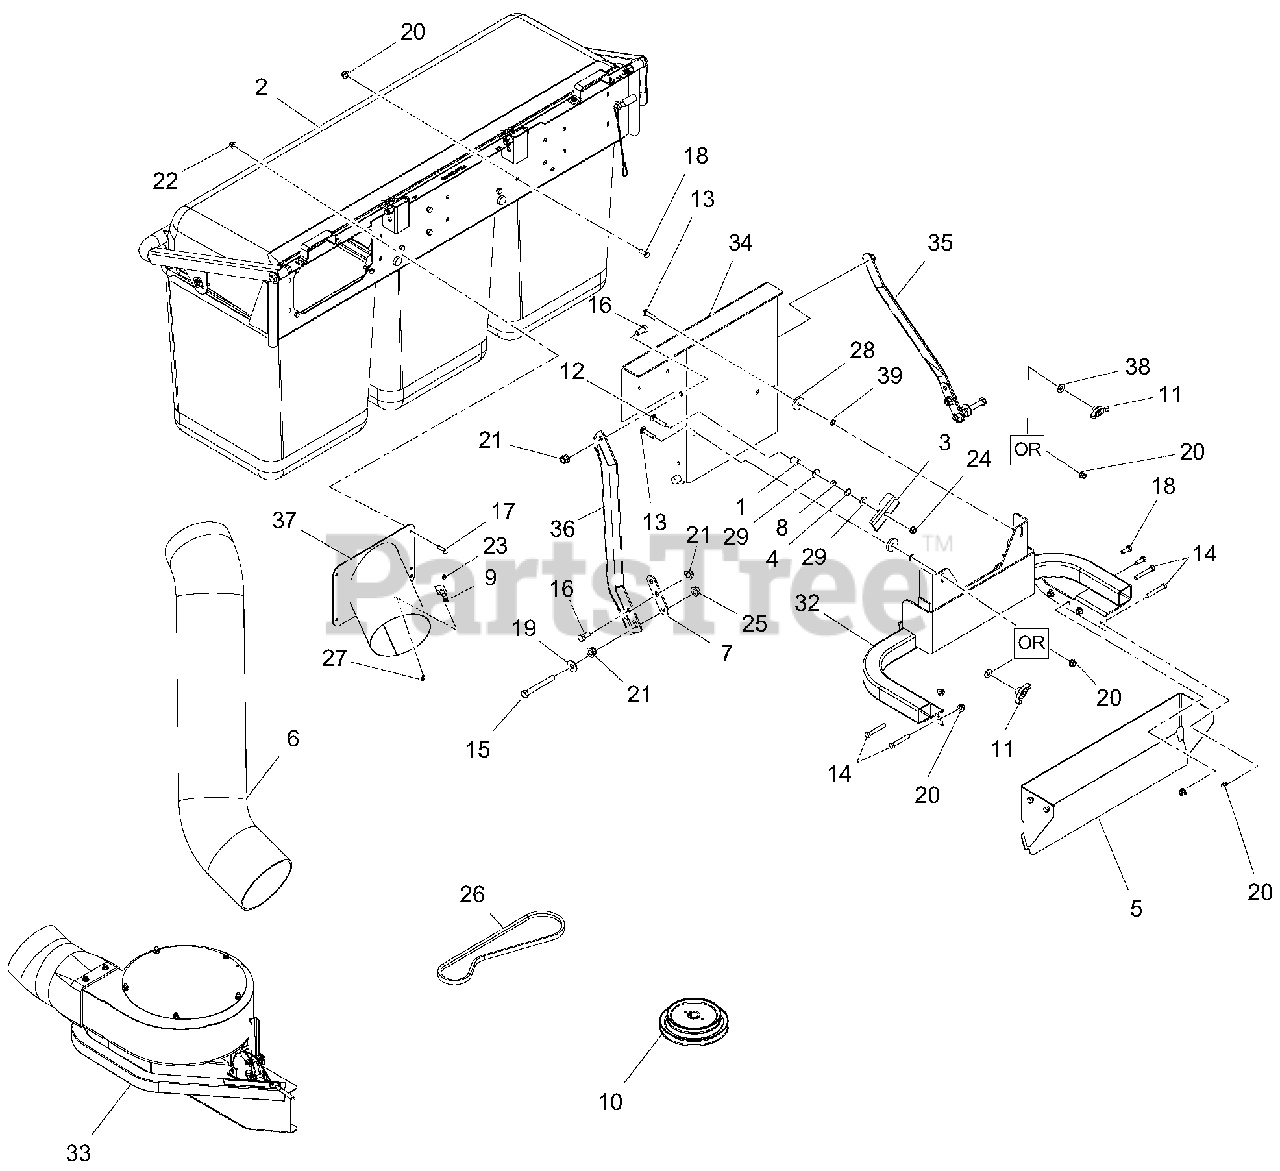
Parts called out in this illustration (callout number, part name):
1	BSHG, SPCR .41 X .75 X .88 PM
2	RECEPTACLE, HUMBOLDT 3-BAG (12BU)
3	LATCH, BAGGER UPPER MOUNT-BLACK
4	WAVE WASHER .640 X .875 X .125 FH
5	SHIELD, HEAT, MUFFLER, BAGGER-BLACK
6	BAGGER HOSE, 38"
7	LINK, OFFSET,BAGGER BRACE-BLACK
8	BSHG, SLV .377X.624X.235
9	LATCH, THUMB
10	SHEAVE, DOUBLE
11	KNOB, WING .38-16 UNC NYL/TALC
12	@BLT-RDHDSQNK .38-16X2.00 G5 Y
13	@BLT-RDHDSQNK .38-16X1.75 G5 YWZC
14	@BLT-HEX .38-16X2.50 GR5 YWZC
15	@BLT-HEX .50-13X4.25 GR5 YWZC
16	@BLT-HEX .50-13X1.00 GR5 YWZC
17	@BLT-HEX .31-18X1.00 GR5 YWZC
18	@BLT-HEX .38-16X1.00 GR5 YWZC
19	@WSHR-FL-STL.563X1.38X.109YWZC
20	NUT-LK-NYL-FLG .38-16 YWZC
21	NUT-LK-NYL-FLG .50-13 YWZC
22	NUT-LK-NYL-FLG .31-18 YWZC
23	@NUT-LK-NYL #10-24 YWZC
24	@NUT, LK-TOP-FLG .38-16 YWZC
25	NUT .50-13 WIZ FLANGE
26	V-BELT, 4L WRAPPED CLUTCHING
27	@SCR-MCH 10-24X.50 HWH YWZC
28	WSHR-FL-STL .406X1.50X.245 YWZC
29	@WSHR-FL-STL.438X1.00X.083 YWZC
32	MOUNT, BAGGER PT200-BLACK
33	BLOWER ASSEMBLY, SERVICE
34	UPPER MOUNT, 3-BAG
35	WLDMT, BAGGER BRACE LH,200/400-BLACK
36	WLDMT, BAGGER BRACE RH,200/400-BLACK
37	ADAPTOR, 200 SERIES INLET-BLACK
38	WSHR-FL-STL .438X1.00X.083 YWZC
